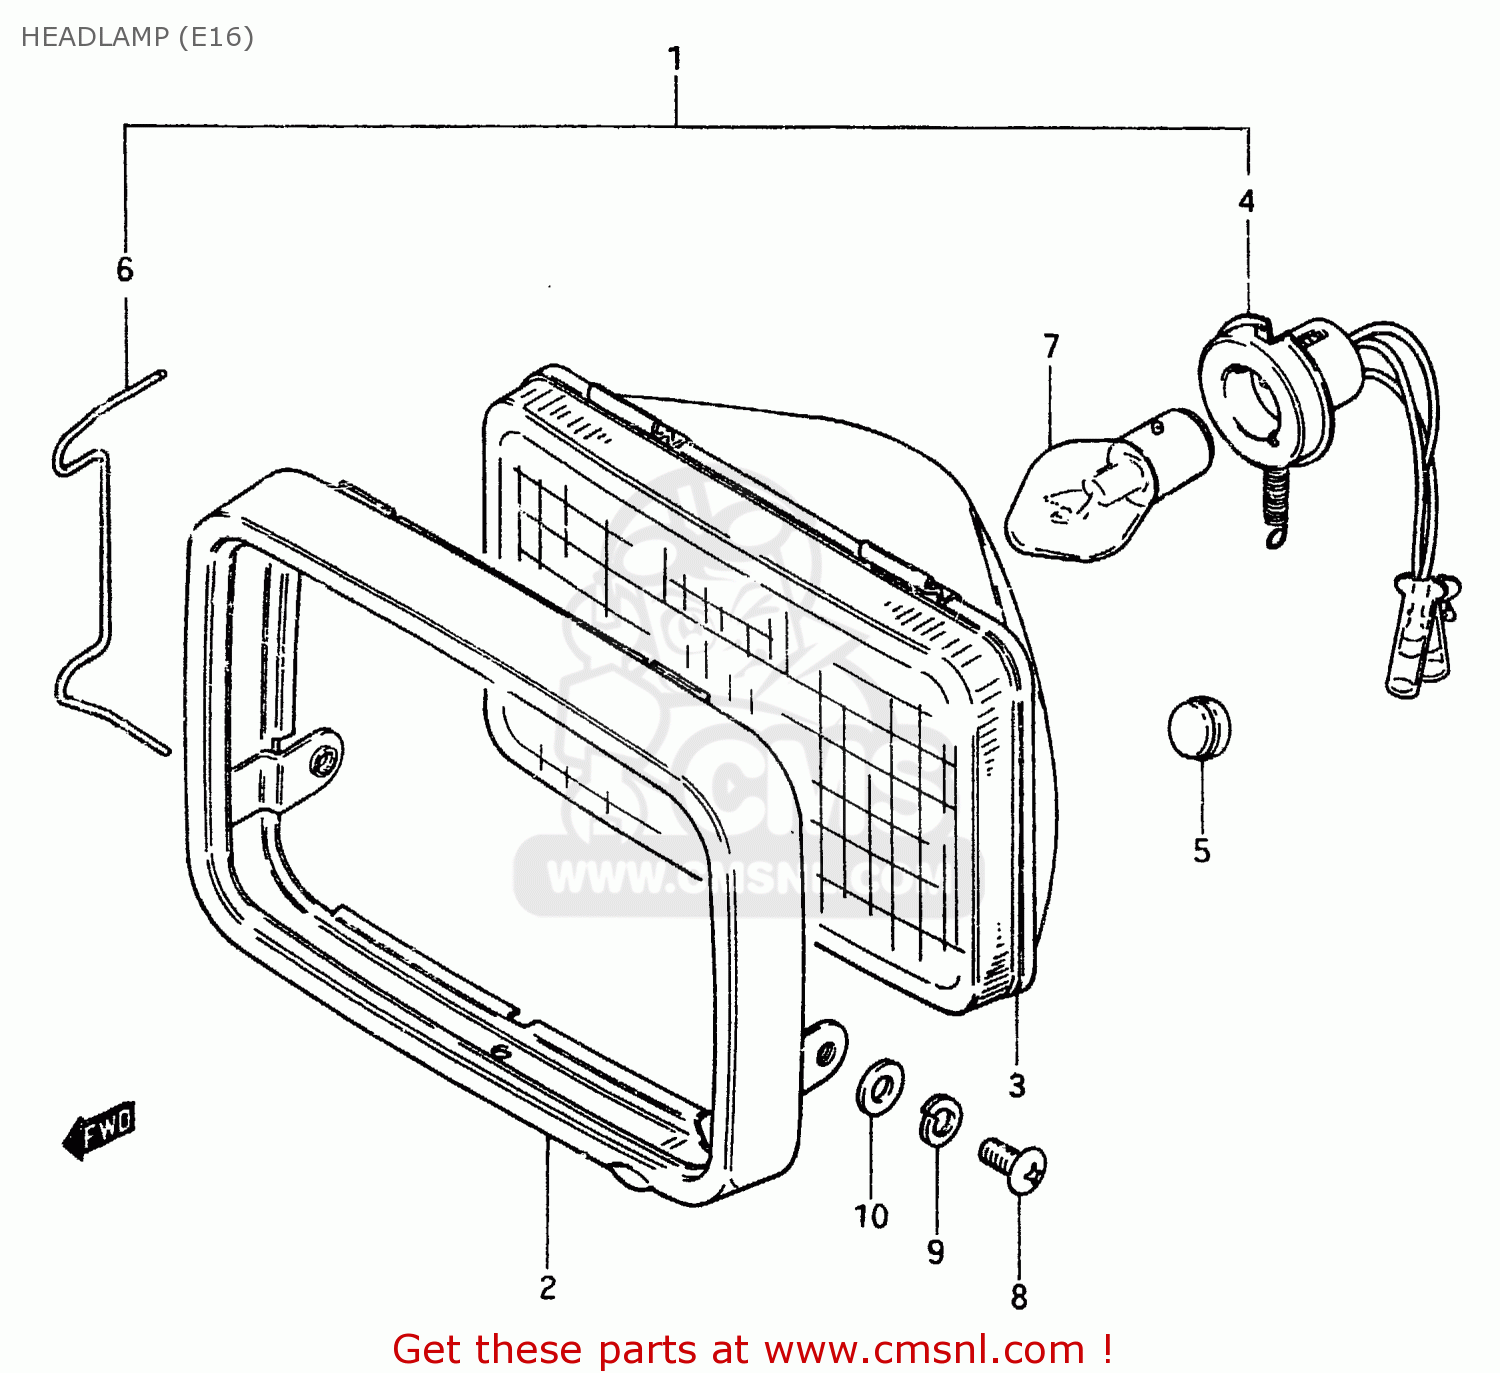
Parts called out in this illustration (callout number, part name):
1	HEADLAMP ASSY
2	RIM
3	UNIT
4	SOCKET
5	CAP
6	SPRING
7	BULB (6V,25/25W)
8	SCREW
9	LOCK WASHER
10	WASHER
